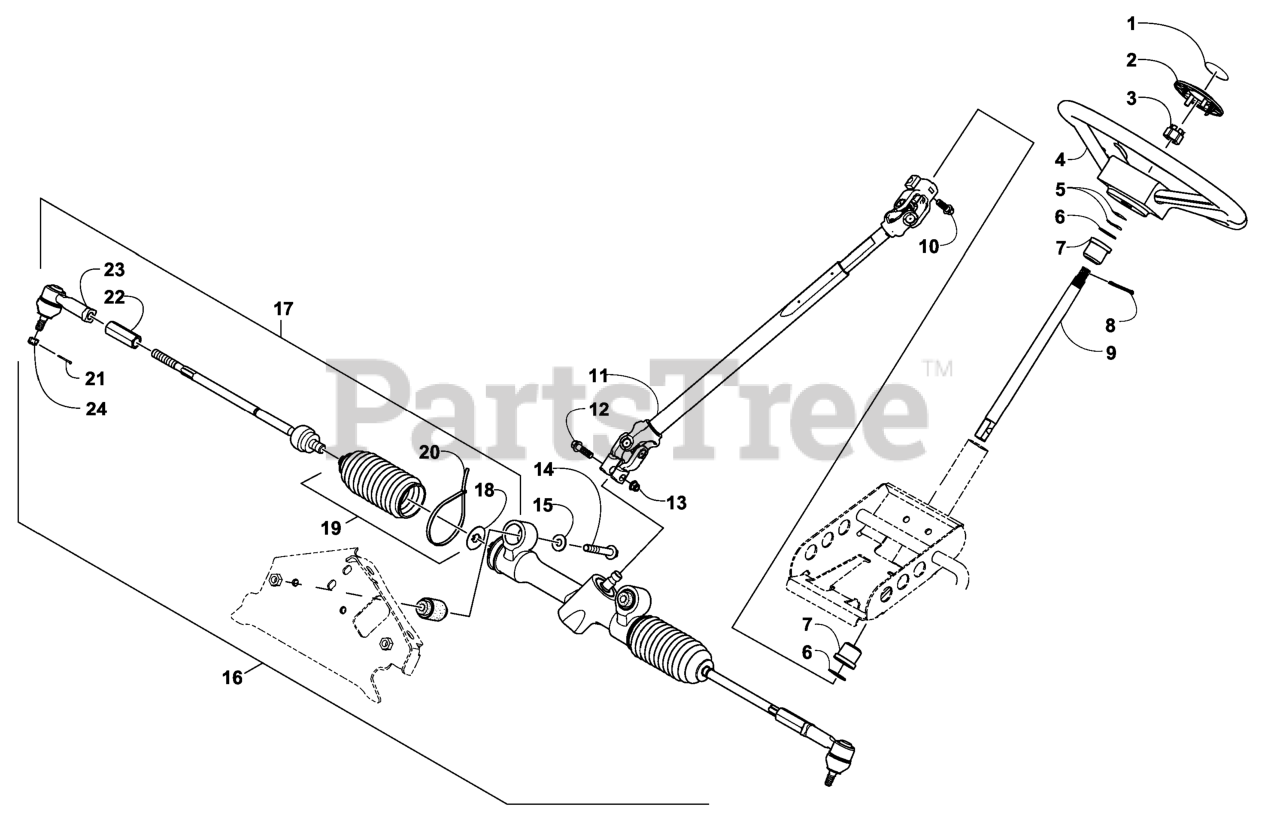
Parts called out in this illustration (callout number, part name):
1	DECAL-STEERING WHEEL
2	CAP-HUB, STEERING WHEEL
3	NUT-HH, SLOTTED
4	WHEEL-STEERING
5	WASHER-BELLEVILLE
7	BUSHING-STEERING
8	CLIP-STEERING WHEEL
9	SHAFT-STEERING WHEEL
10	BOLT-PINCH
11	SHAFT-LOWER STEERING
12	SCREW-HFH
13	NUT-HHF, LOCK, (NI)
15	WASHER-FLAT, HRDND
16	STEERING ASM KIT (RACK AN
17	TIE ROD KIT (INNER-W/ ROD
18	PLATE-LOCK, STEERING RACK
19	BOOT KIT (RACK AND PINION
20	TIE-CABLE
22	NUT-HEX, JAM
23	ROD END KIT
24	NUT-HH, CASTLE
